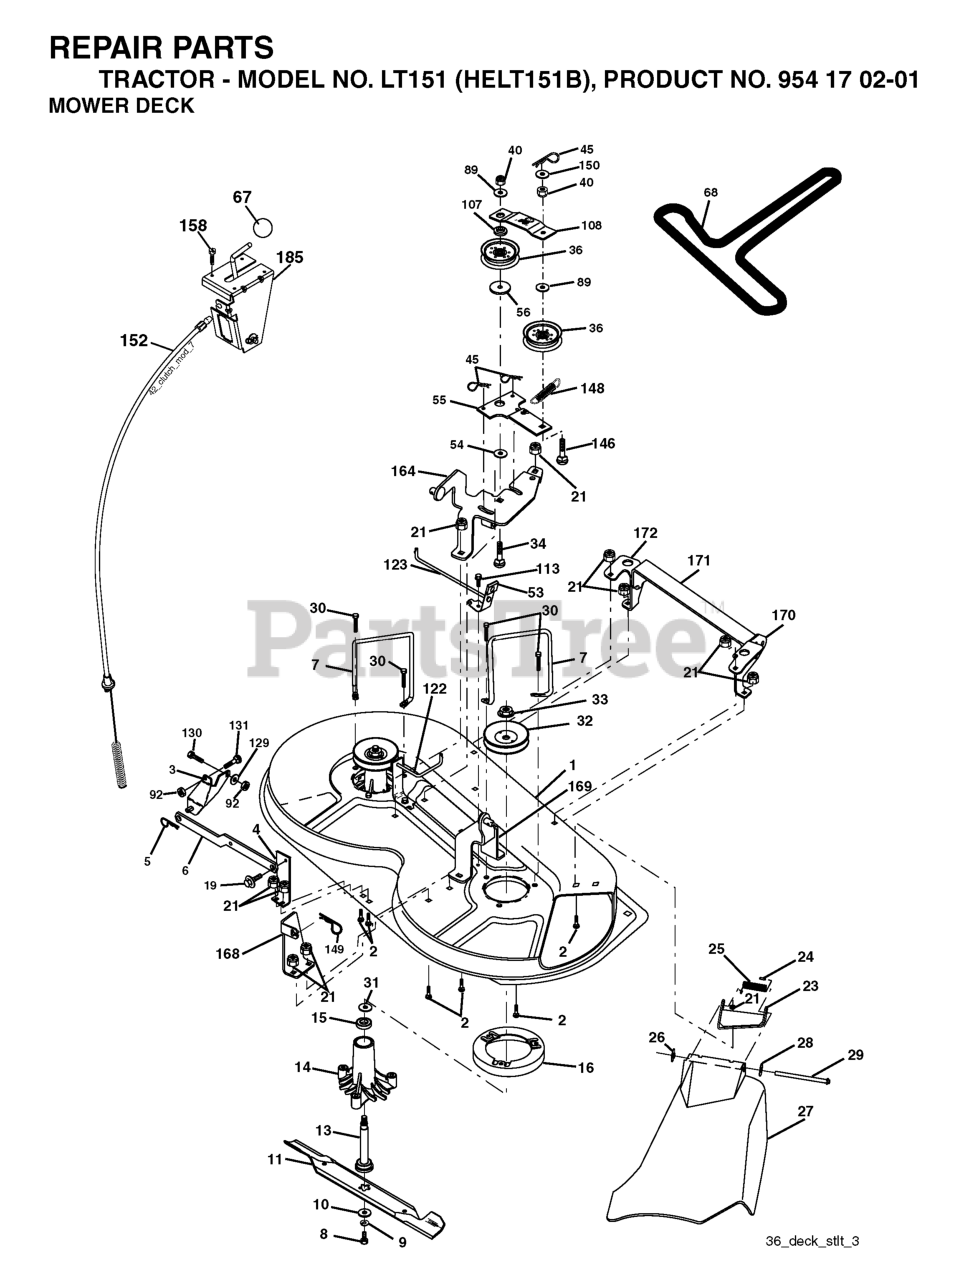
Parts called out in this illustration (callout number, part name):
2	RP BOLT 5/16-18 X3/4 ZN/YEL GR
3	BRKT ASM SWAY BAR
5	RETAINER-SPRNG RB
6	BAR SWAY DECK
8	BLADE BOLT
9	LOCKWASHER
10	WASHER.BLADE
11	BLADE, HI-LIFT 36" PREMIUM
13	SHAFT ASM VENT
14	HOUSING.MANDREL.VENTED (MACHD)
16	STRIPPER.MANDREL.ROUND.BLACK
19	BOLT SHD 5/16-18
21	LOCKNUT
23	BRACKET ASM DEFLECTOR
24	CAP-SLEEVE LT
25	SPRING TORSION
26	NUT PUSH M
27	CONSOLE.STLT.5SP.BLK
28	Washer 11/32 x 5/8 x 16 Ga SD
29	HINGE ROD
30	SCREW, WASHER HEAD
31	WASHER.SPACER.MANDREL
32	PULLEY, MANDREL
33	NUT, FLG TOPLOCK 9/16"
36	FLAT IDLER PULLEY
45	RETAINER M
53	BRAKE ASSEMBLY
56	SPACER.RETAINER.MOWER
67	KNOB T (3/8 HOLE)
68	V-BELT.MOWER.
89	WASHER
92	NUT
107	SPACER.IDLER.ARM
108	STIFFENER.IDLER.ARM
113	Screw 5/16-18 x 1/2 Hex, Self Tapping 5/16-18 x 1/2
129	WASHER
131	BOLT D
146	BOLT, CARRIAGE IDLER
148	IDLER RETURN SPRING
149	SPRING.RETAINER.YELLOW.ZINC
158	SCREW
171	BRACE.SUPT.SUSP.FRT.CRD
185	HEAD ASM. CABLE CLUTCH
